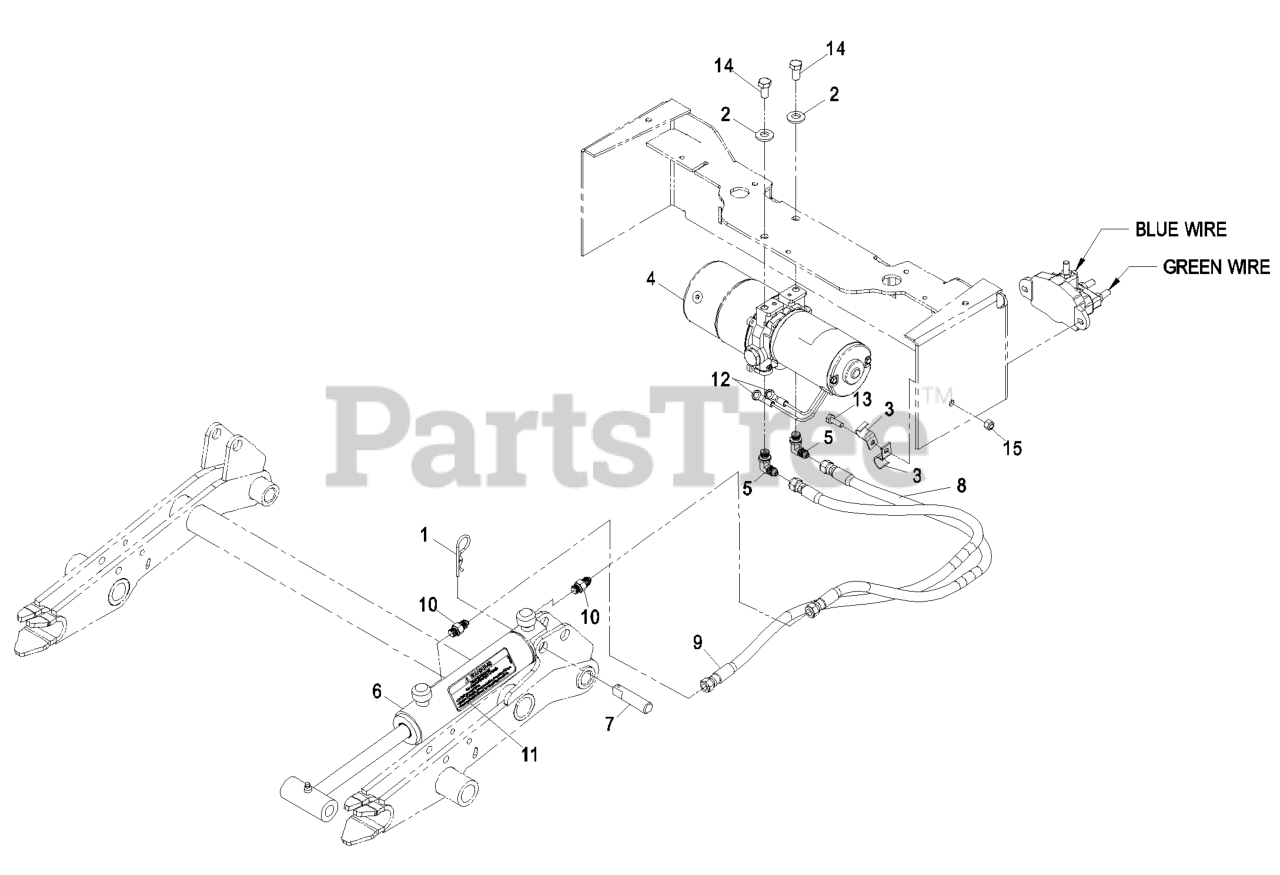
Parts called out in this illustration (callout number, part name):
1	PIN-COTTER
2	WASHER-BELLEVILLE
3	CLIP-HALF, LOOM
5	ADAPTER,90 DEG
6	ASM,FMZ HYD CYLINDER
7	PIN,CYLINDER MOUNT RR
8	ASM,HYDRAULIC HOSE -4
9	ASM,HYDRAULIC HOSE -4
10	ADAPTER,STRAIGHT ORIFICED
11	DECAL,HIGH PRESSURE OIL
12	TERMINAL,RING 5/16" INSUL
13	SCREW-HH
14	SCREW-HH
15	NUT-LOCK, NI
